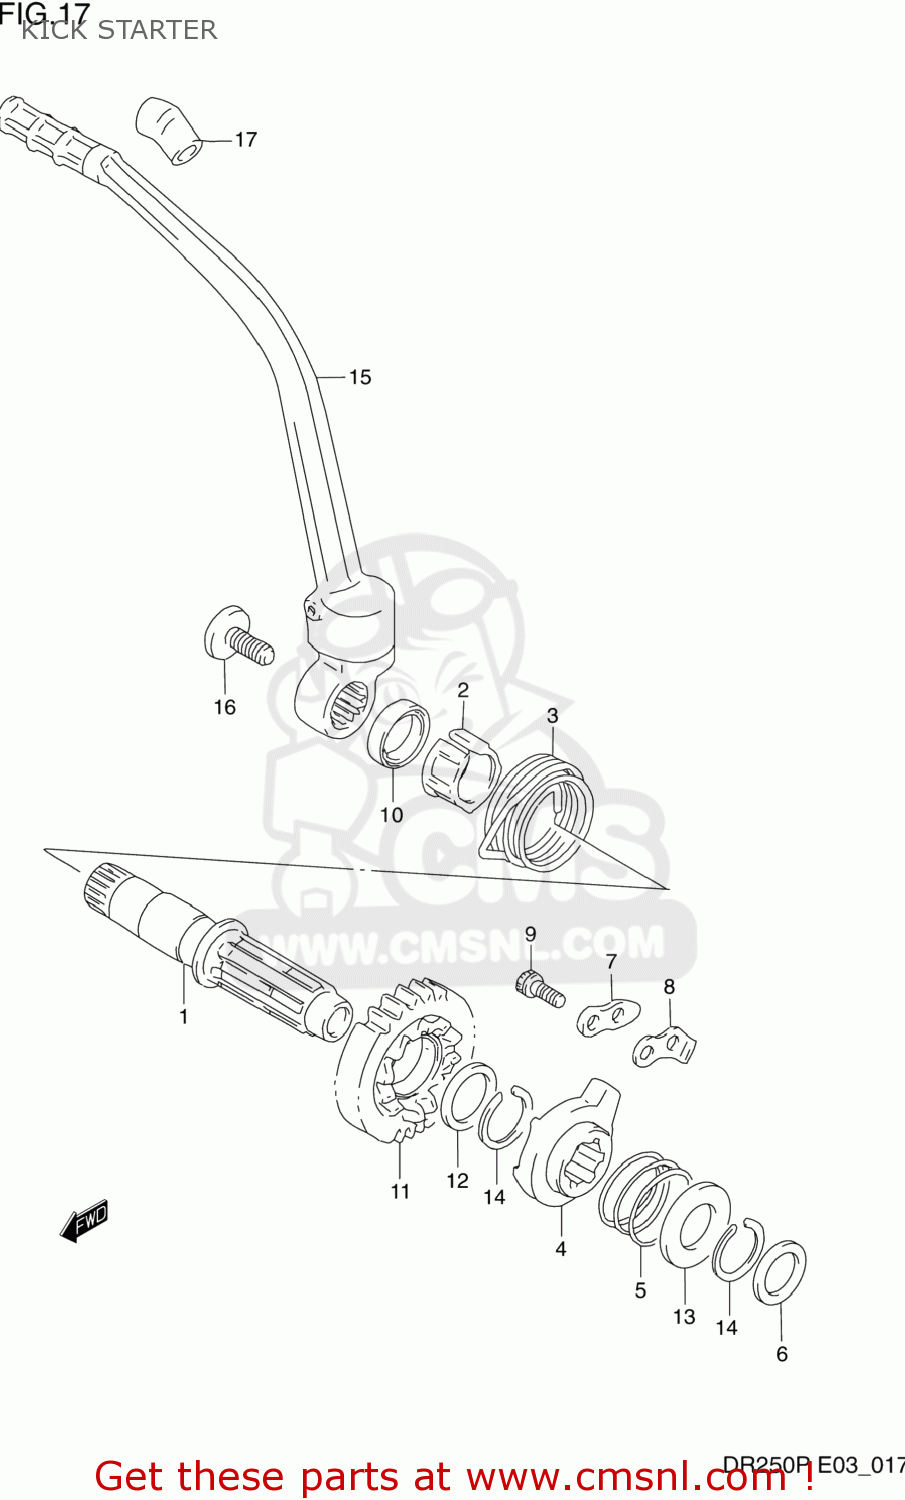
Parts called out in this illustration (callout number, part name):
1	SHAFT,KICK STARTER
2	GUIDE,KICK STARTER SFT SPRING
3	SPRING
4	STARTER,KICK
5	SPRING
6	WASHER,THRUST
7	GUIDE,KICK STARTER
8	STOPPER,KICK STARTER
9	BOLT,KICK START STOPPER
10	SEAL,OIL(20X27X6)
11	GEAR,KICK STARTER NO.2
12	SHIM
13	WASHER,THRUST
14	CIRCLIP
15	LEVER ASSEMBLY,KICK STARTER
16	BOLT(8X14)
17	COVER,KICK STARTER LEVER
